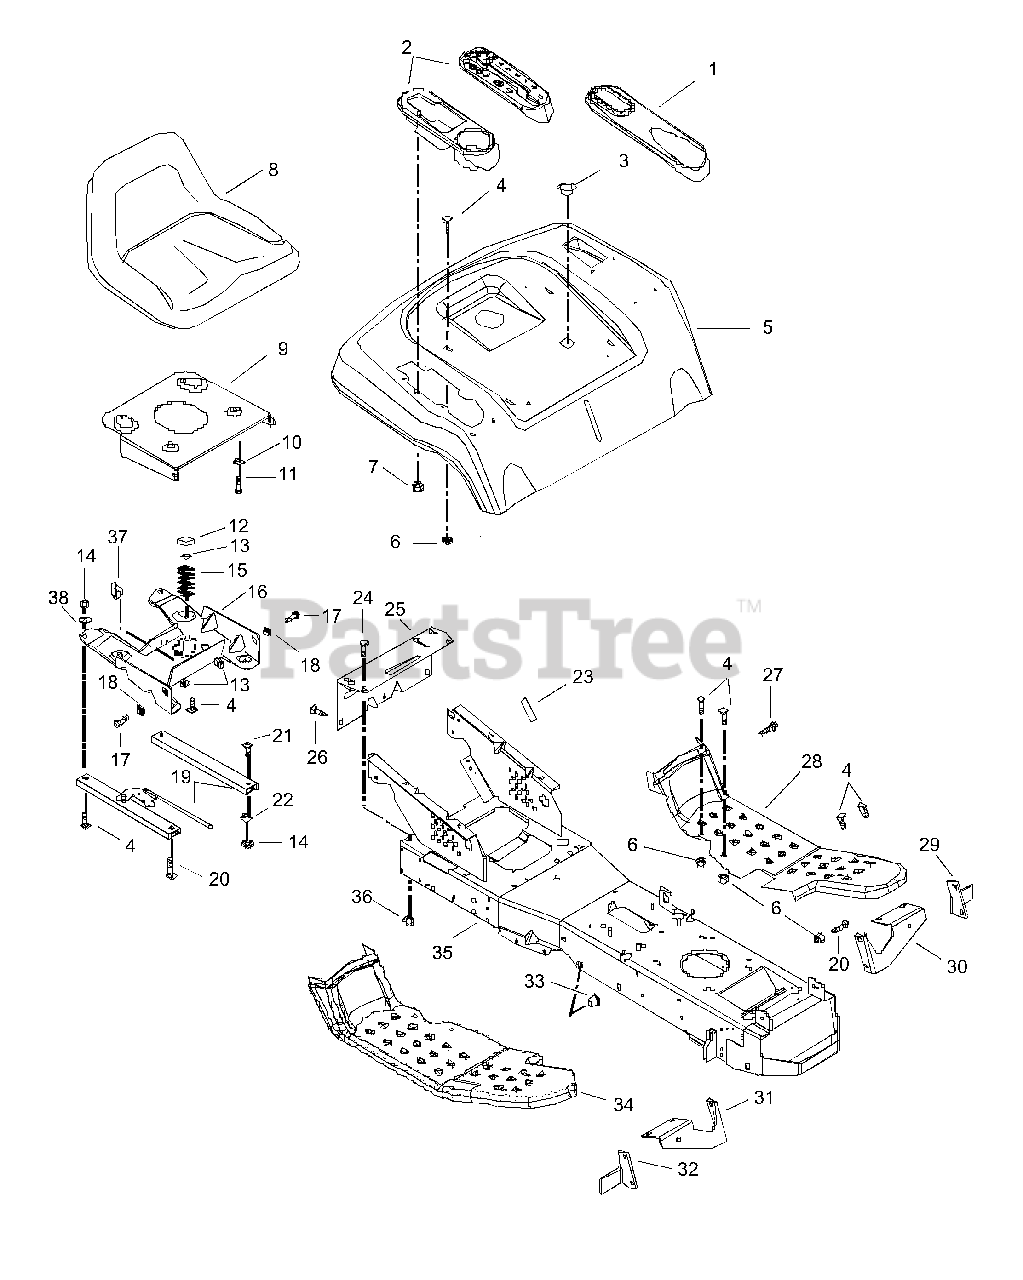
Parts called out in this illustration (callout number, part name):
1	Insert-Lift
2	Holder-Beverage
3	Snap Bushing
4	Bolt-Round Head Square Neck .31-18 x .62
5	Rear Deck
6	Nut-Locking Flange .312-18
7	Nut-Self-Threading Fits .25 Stud
8	Seat-V1400 Med Weltless
8	Seat-V1500 Hi Weltless
9	Seat Pivot Plate
10	Washer-Lock .312 x .097
11	Bolt-Hex .31-18 x .75 Grade 5
12	Tube Cap
13	Nut-Locking Center .312-18
14	Nut-Hex .312-18
15	Spring-Compression .148 x 1.23 x 2.4
16	Seat Box
17	Bolt-Hex .31-18 x .75 Grade 5
18	Bushing-Flange .325 x .465 x .333 x .685
19	Seat Slides
20	Bolt-Round Head Square Neck .31-18 x .75 Grade 5
21	Screw-Cap Button Head .31-18 x .50 Grade 5
22	Washer-Lock External .313 x .030
23	Pad-Battery
24	Bolt-Round Head Square Neck .38-16 x .75 Grade 5
25	Draw Bar
26	Screw-Tapping .312-18 x .75
27	Screw-Tapping .312-18 x .50
28	Footrest-Left Hand
29	Bracket-Mower Height Left Hand
30	Brace-Foot Rest Left Hand
31	Brace-Foot Rest Right Hand
32	Bracket-Mower Height Right Hand
33	Bushing-Flange .515 x .750 x .745 x 1.00
34	Footrest-Right Hand Hydro
35	Main Frame
36	Nut-Center Locking .375-16
37	Clip-Harness
38	Washer-Locking .312
